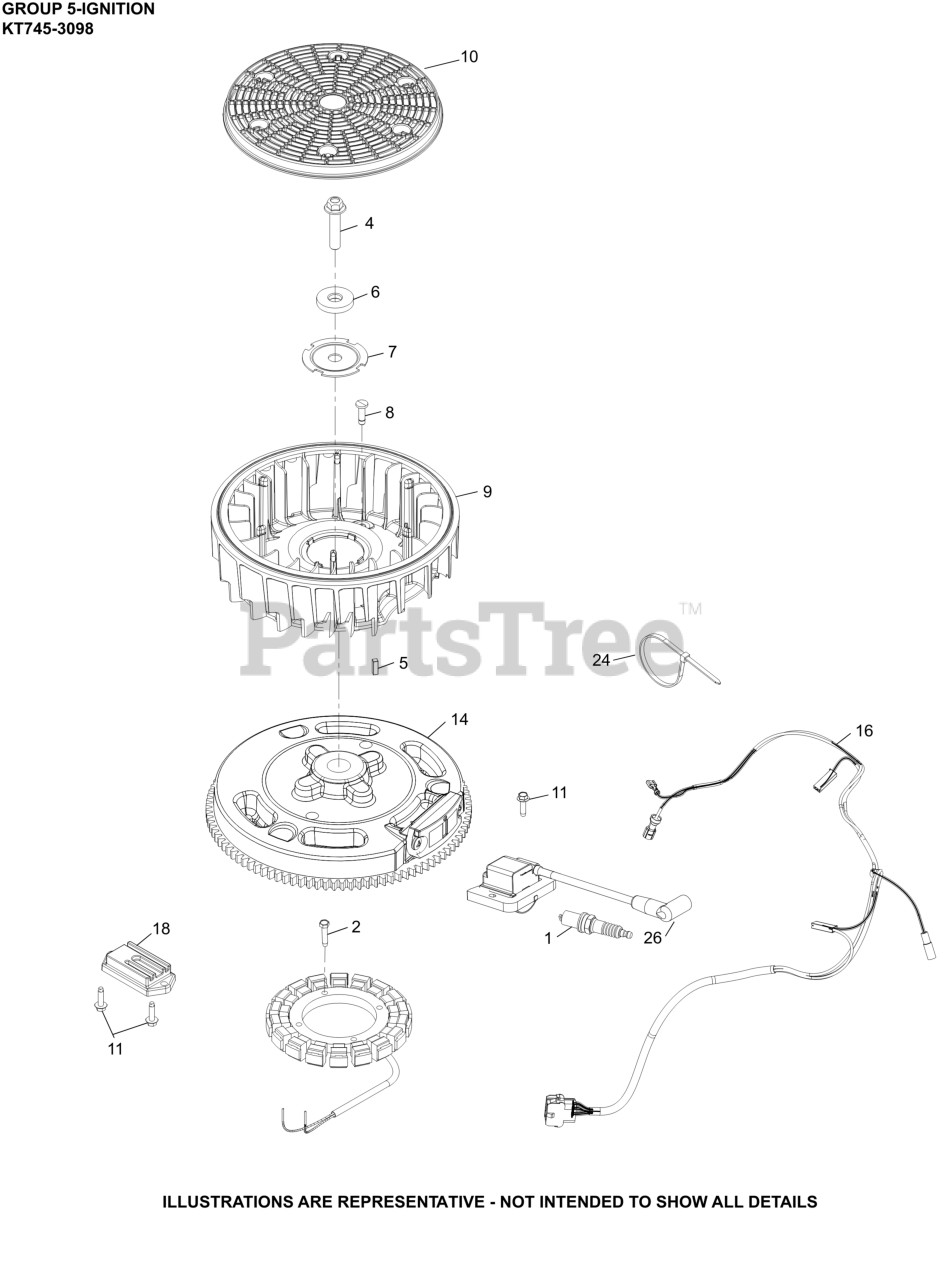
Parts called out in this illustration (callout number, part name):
1	SPARK PLUG, RFI
2	SCREW, THREAD FORMING
4	SCREW, HEX FLANGE
5	KEY, SQUARE
6	WASHER, FLAT
7	PLATE, FAN MOUNTING
8	RETAINER, FLYWHEEL FAN
10	SCREEN, GRASS
11	SCREW, THD FRM-USE 25 086 473-S
14	FLYWHEEL ASSEMBLY
16	HARNESS, WIRING ASSEMBLY
18	REG/RECT12/15A HALF-WAVE STD-(#2540347S)
26	MODULE, MAGNETO DIGITAL IGNITION
